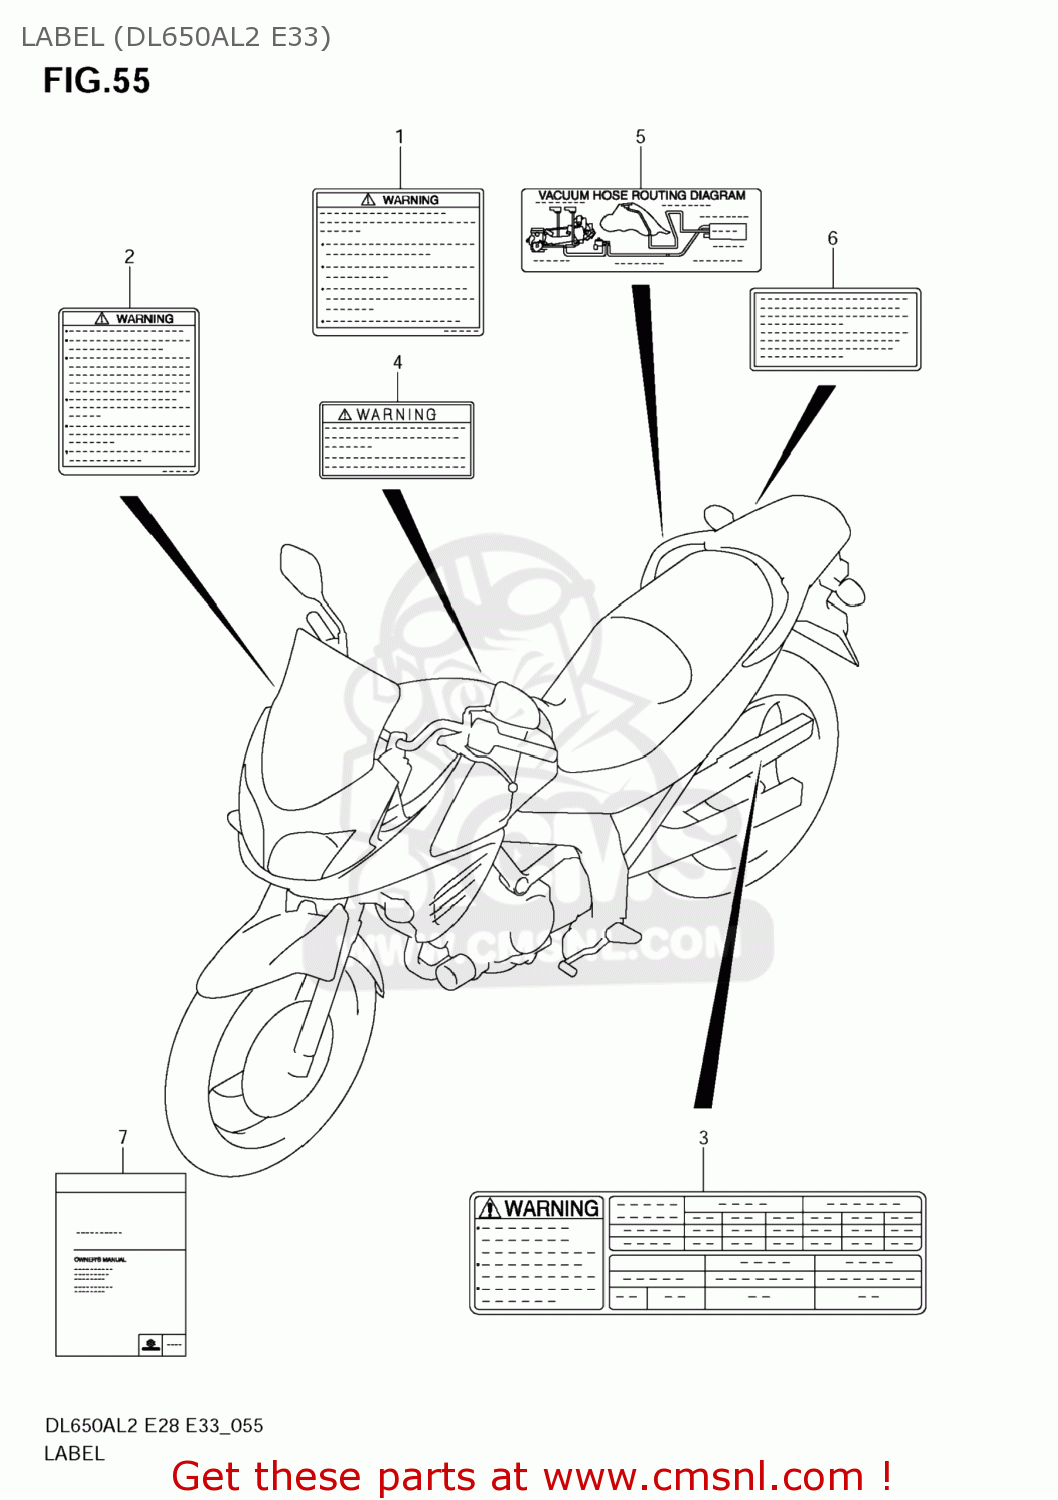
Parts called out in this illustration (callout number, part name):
1	LABEL,GENERAL WARNING
2	LABEL,SCREEN
3	LABEL,TIRE INFORMATION
4	LABEL,WARNING STEERING
5	LABEL,VACUUM HOSE ROUTING
6	LABEL,MANUAL NOTICE
7	MANUAL,OWNER'S
